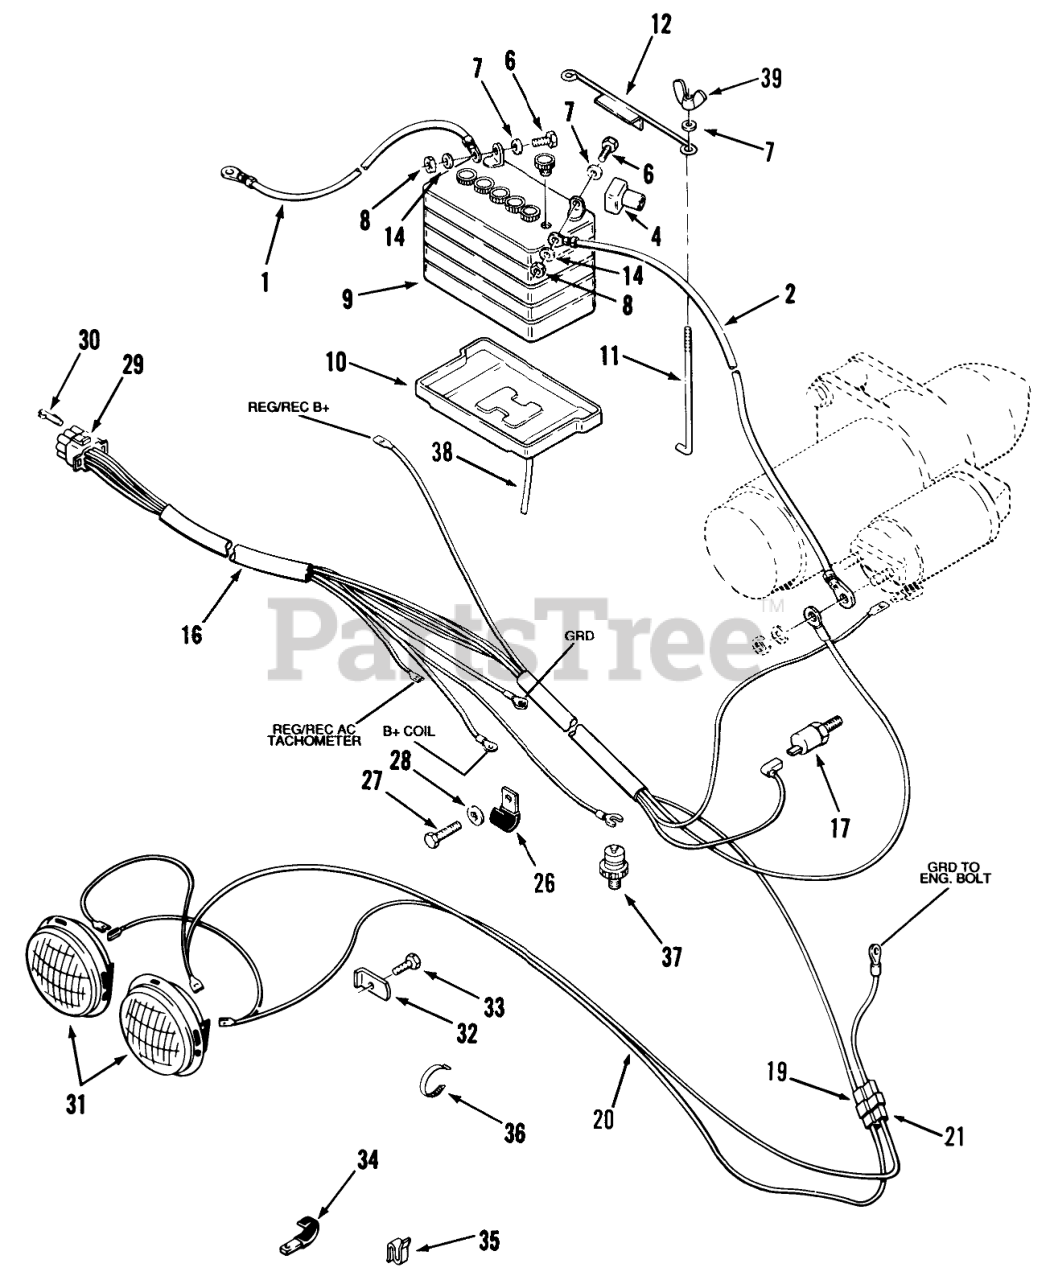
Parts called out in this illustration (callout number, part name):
1	ASS'Y-WIRE
2	ASS'Y-WIRE
4	Boot
6	SCREW-HH
7	WASHER-FLAT
8	NUT-LOCK, NI
9	Battery
10	THRUST WASHER
11	HOOK-BATTERY RETAIN
12	HOLDDOWN-BATTERY
14	WASHER-LOCK
16	WIRING HARNESS
17	HIGH TEMPERATURE
19	MALE CONNECTOR
20	HARNESS-HEADLIGHT
21	CONNECTOR BODY
26	CLIP-WIRE
27	SCREW-HWH
28	LOCKWASHER 1/4 IT
29	CONNECTOR CAP
30	CONTACT SOCKET
31	HEADLAMP
32	LOCK-HEADLIGHT
33	Bolt
34	CLIP
35	SPEED CLIP
36	PLASTIC TIE
37	SWITCH
38	TUBE-BATTERY DRAIN
39	NUT-WING
40	ELBOW-45 DEG
